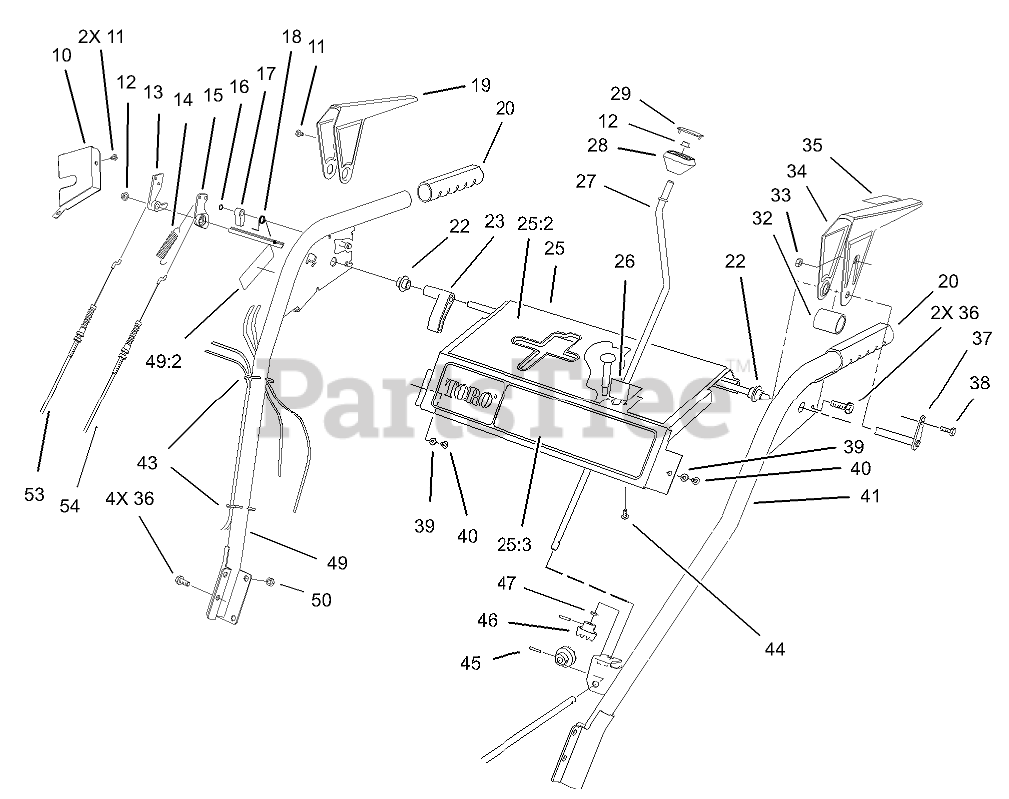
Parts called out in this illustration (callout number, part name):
10	COVER-LOCK, LEVER
11	SCREW-HH
12	RETAINER-PUSH ON
13	TANG-LOCKING
14	SPRING-EXTENSION
15	CAM-RELEASE
16	E-RING-RETAINER
17	LATCH-LOCKING
18	SPRING-TORSION
19	LEVER-TRACTION, RH
20	GRIP-HANDLE
22	BUSHING-LEVER
23	LEVER-TRIP
25	CONTROL PANEL ASM
25:2	DECAL-PANEL, TOP
25:3	DECAL - PANEL FRONT
26	PLATE-GUIDE
27	CRANK-ROD, CHUTE
28	KNOB-CONTROL, CHUTE
29	COVER-KNOB
32	SPACER-LEVER, TRACTION
33	NUT-LOCK, NI
34	LEVER-TRACTION, LH
35	DECAL-LEVER
36	SCREW-HWHTF
37	CROSS ROD ASM
38	SCREW-HWH
39	WASHER-FLAT
40	SCREW-HWHTF
41	LH HANDLE ASM
43	TIE-CABLE
44	SCREW
45	PIN-SPRING
46	GEAR-UNIVERSAL
47	WASHER-RUBBER
49	HANDLE ASM
49:2	DECAL-WARNING
50	NUT-LOCK, NI
53	CABLE-IMPELLER
54	CABLE-TRACTION
